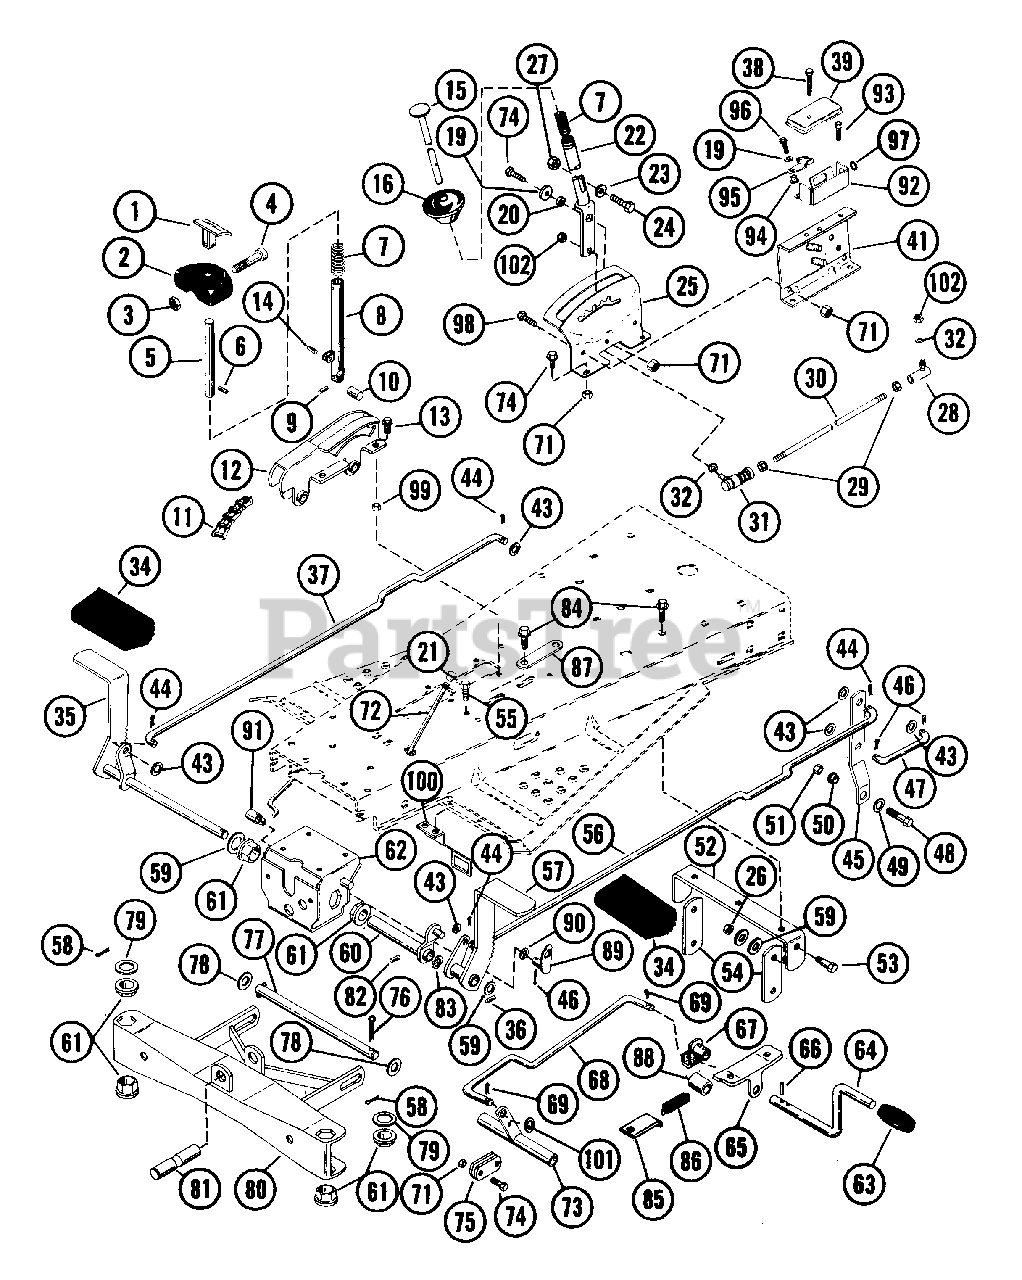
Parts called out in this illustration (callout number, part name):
1	T PLUNGER
2	T HANDLE
3	NUT-LK TOP 10-24 PL
4	BLT-HEX 10-24X1.25 FHPL
6	PIN-ROLL .250X1.25
7	SG-COMP ??X.44X?? WLD 10
8	MOWER LIFT ARM
9	PIN-ROLL .125X.75
11	ROLLER CHAIN
12	MOWER HEIGHT QUAD
13	BLT-HEX .25-20X.50 PL GR2
14	PIN-ROLL .156X.75
15	SHIFT RELEASE HANDLE
16	SHIFT BALL
19	WSHR-FL-STL .38X.875X.083 PL
20	SPACER BUSHING .5 X .32 X .21
22	SHIFT LEVER
23	WSHR-FL-STL .281X1.250X.048PL
24	BLT-HEX .25-20X1.25
25	SHIFT CONTROL SEGMENT
26	NUT-LK-JAM-CTR .375-16 PL
27	NUT-LK TOP .250-20 PL
28	BALL JOINT
29	NUT-HEX .312-24 PL
30	SHIFT LINK
31	SNAP IN BALL JOINT
32	WSHR-LK .312X.097 PL HVY
34	PEDAL COVER
35	BRAKE LEVER
36	PIN-ROLL .125X1.00
37	BRAKE ROD
38	SCR-TAP 12-14X1.25 CROVH PL 1A
41	SWITCH BRACKET
43	WSHR-FL-STL .382X.812X.023 PL
44	PIN-COTR .09X.75 PL
45	CLUTCH LINK BAR
46	PIN-COTR .12X1.0 PL
47	CLUTCH LINKAGE ROD
48	BLT-HEX .38-16X.75 PL GR2
49	WSHR-FL-STL .630X1.005X.062 PL
50	SHOULDER SPACER
51	NUT-LK-CTR .375-16 GR A PL
52	HANGER BRACKET
53	SHOULDER BOLT .50 X .31
54	HANGER LINK
55	BLT-SERHFWH .25-20X.50 PL
56	CLUTCH ROD
57	CLUTCH BRAKE LEVER
58	PIN-COTR .12 X 1.25 PL
59	WSHR-FL-STL .505X.875X.024 PL
60	CLUTCH BRAKE LEVER
61	FLANGE BUSHING
62	AXLE SUPPORT
64	MOWER CLUTCH PEDAL
65	MOWER CLUTCH BRACKET
66	PIN-ROLL .188X1.00
67	OVER CENTER LEVER
68	MOWER CLUTCH LINK
69	PIN-COTR .09X.75 PL
71	NUT-LK .312-18 GR A PL
72	PARKING BRAKE ROD
73	MOWER CLUTCH LEVER
74	BLT-HEX .31-18X.75 PL GR2
75	FRONT LINK
76	PIN-HAIR INT .14X.4X2.75
77	HANGER PIN
78	WSHR-FL-STL .531X1.062X.095 PL
79	WSHR-FL-STL .755X1.375X.062 PL
80	FRONT AXLE
81	AXLE PIVOT PIN
82	PIN-ROLL .188X.88
83	WAVE WASHER .531X.781X.125FH
84	BLT-SCRHFWH .38-16X.50 PL
85	SPRING CLIP
86	SG-TENS .062X.437X.312 WLD 12
87	GUIDE PLATE
89	BRAKE LATCH
90	WSHR-FL-STL .511X1.441X.125 PL
91	BRAKE RELEASE LEVER
92	SWITCH HOUSING
93	SCR-TAP 10-24X.375 CRPH 1A
94	BSHG, FLG .325X.499X.26X.88
95	CAM NO SCRAP
96	BLT-SERHFWH .31-18X.75 PL
97	GROMMET, .31 ID
98	BLT-HEX .31-18X.50 PL GR2
99	NUT-LK-CTR .250-20 PL
100	SWITCH BRACKET
101	WSHR-FL-STL .380X.626X.033
102	NUT-LK .312-24
